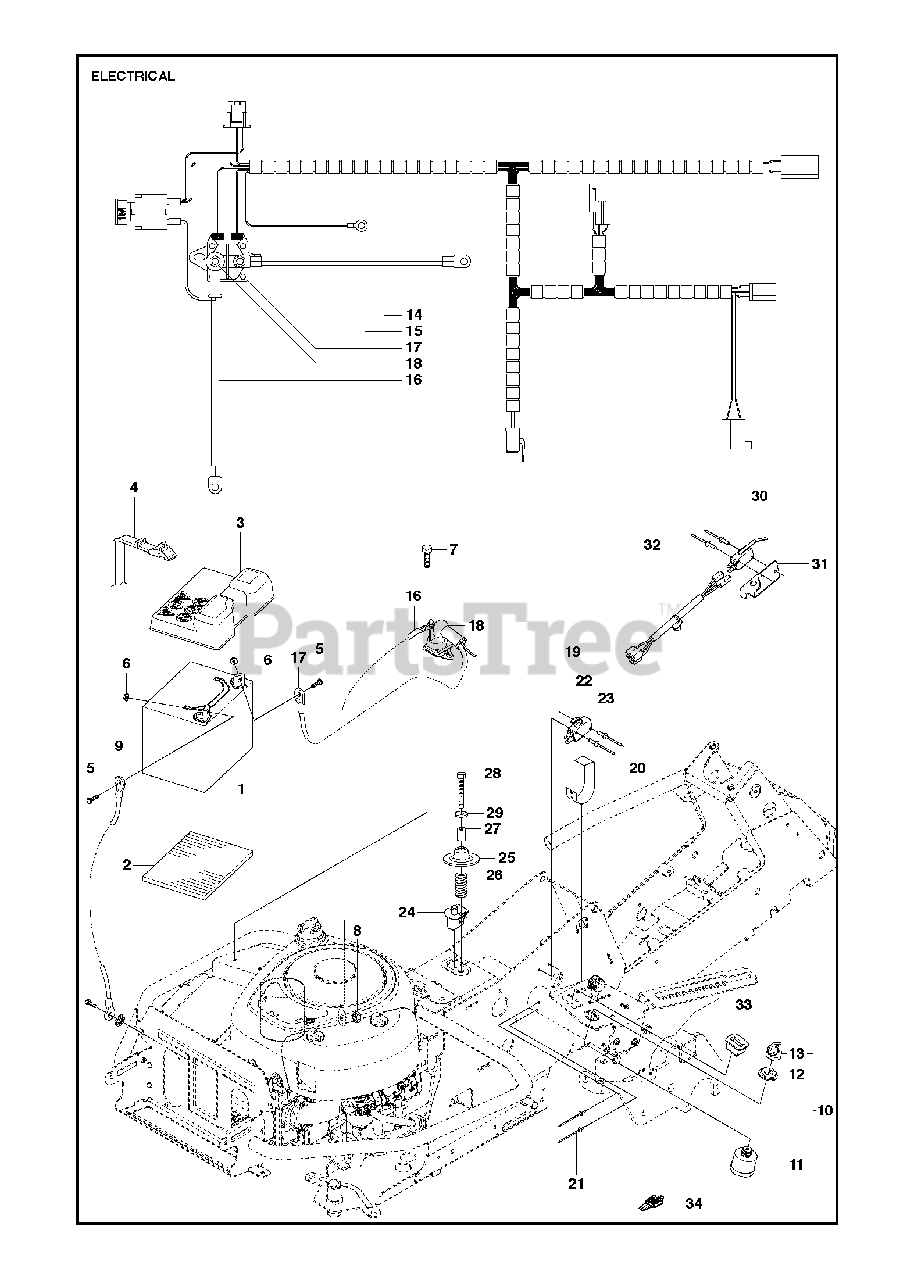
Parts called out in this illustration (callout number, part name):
5	SCREW EHHM
10	IGNITION SWITCH
11	IGNITION SWITCH
12	NUT
13	IGNITION KEY
15	Cable
19	WIRING
27	SPACER TUBE
28	SCREW
29	WASHER BRB 8.4X17
30	MICRO SWITCH
33	HOUR METER
